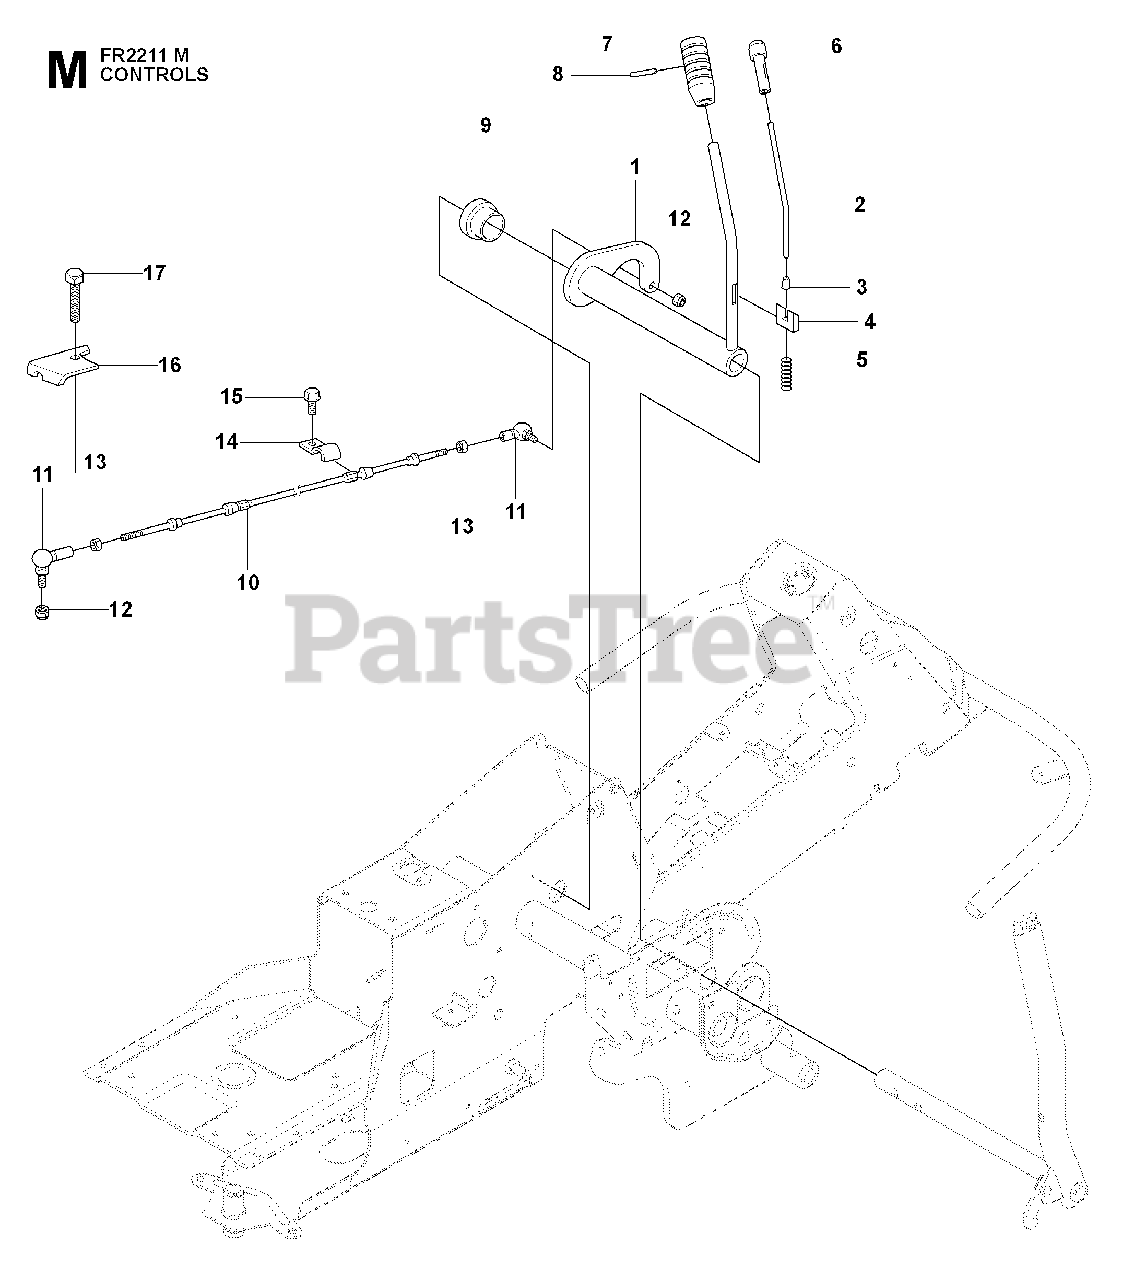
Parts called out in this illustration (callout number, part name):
3	END PIECE
8	SPRING PIN 3X24
9	BUSH
10	%ROD
11	CONNECTOR
12	LOCKNUT M5
